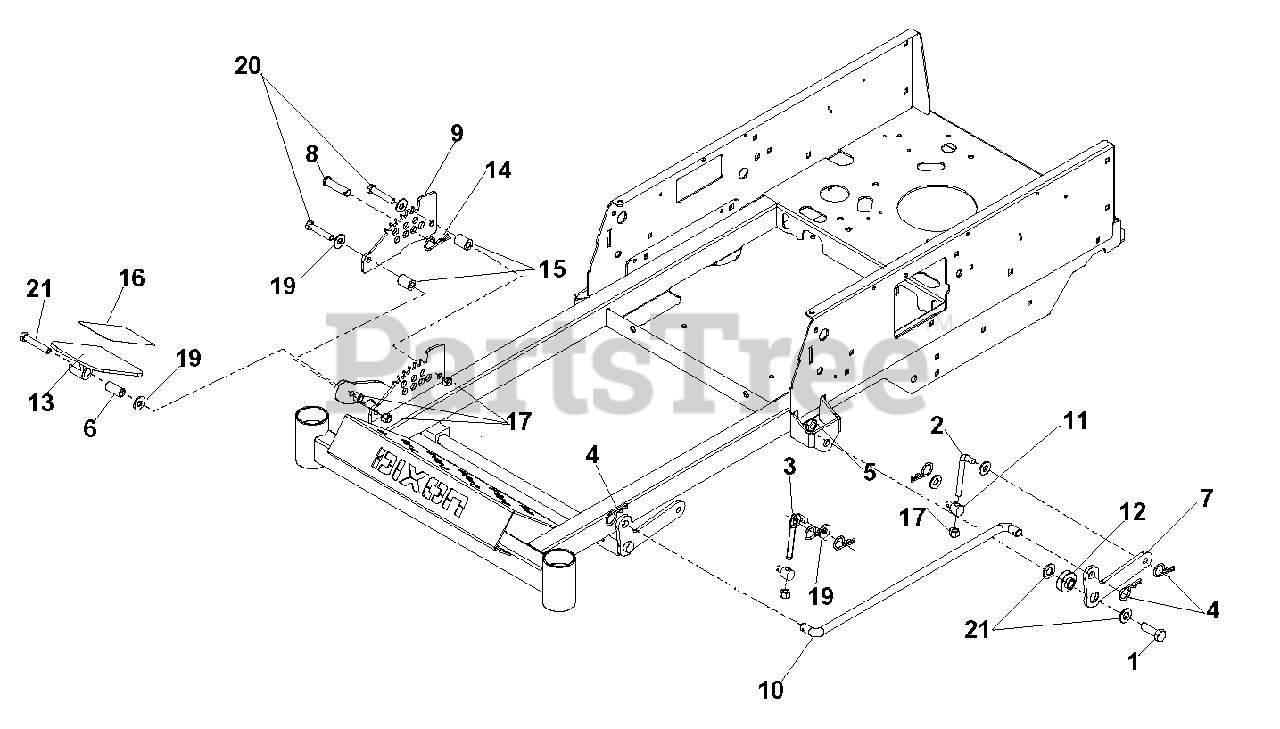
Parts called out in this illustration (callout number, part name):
1	HCS 1/2-13 X 1-1/2 GR 5 ZD
2	L ROD 3-1/8"
3	L-ROD 3.5
4	PIN, COTTER 1 3/4
5	NUT, 1/2-13 THIN PROF NYL
6	BUSHING
7	REAR LIFT LINK
8	CLEVIS PIN 1/2 X 2 LG
9	LIFT QUADRANT (DK BLUE)
10	LINK DECK LIFT
12	IDLER SPACER
13	FOOT PEDAL (PLATED)
14	STAINLESS COTTER
16	FOOT PAD
17	NUT 3/8-16 NYLOC
18	WASHER 1/2" FLAT
19	WASHER 3/8 FLAT
20	HCS 3/8C X 2
21	HCS 3/8C X 2 1/4
22	WASH USS FLAT 1/2
